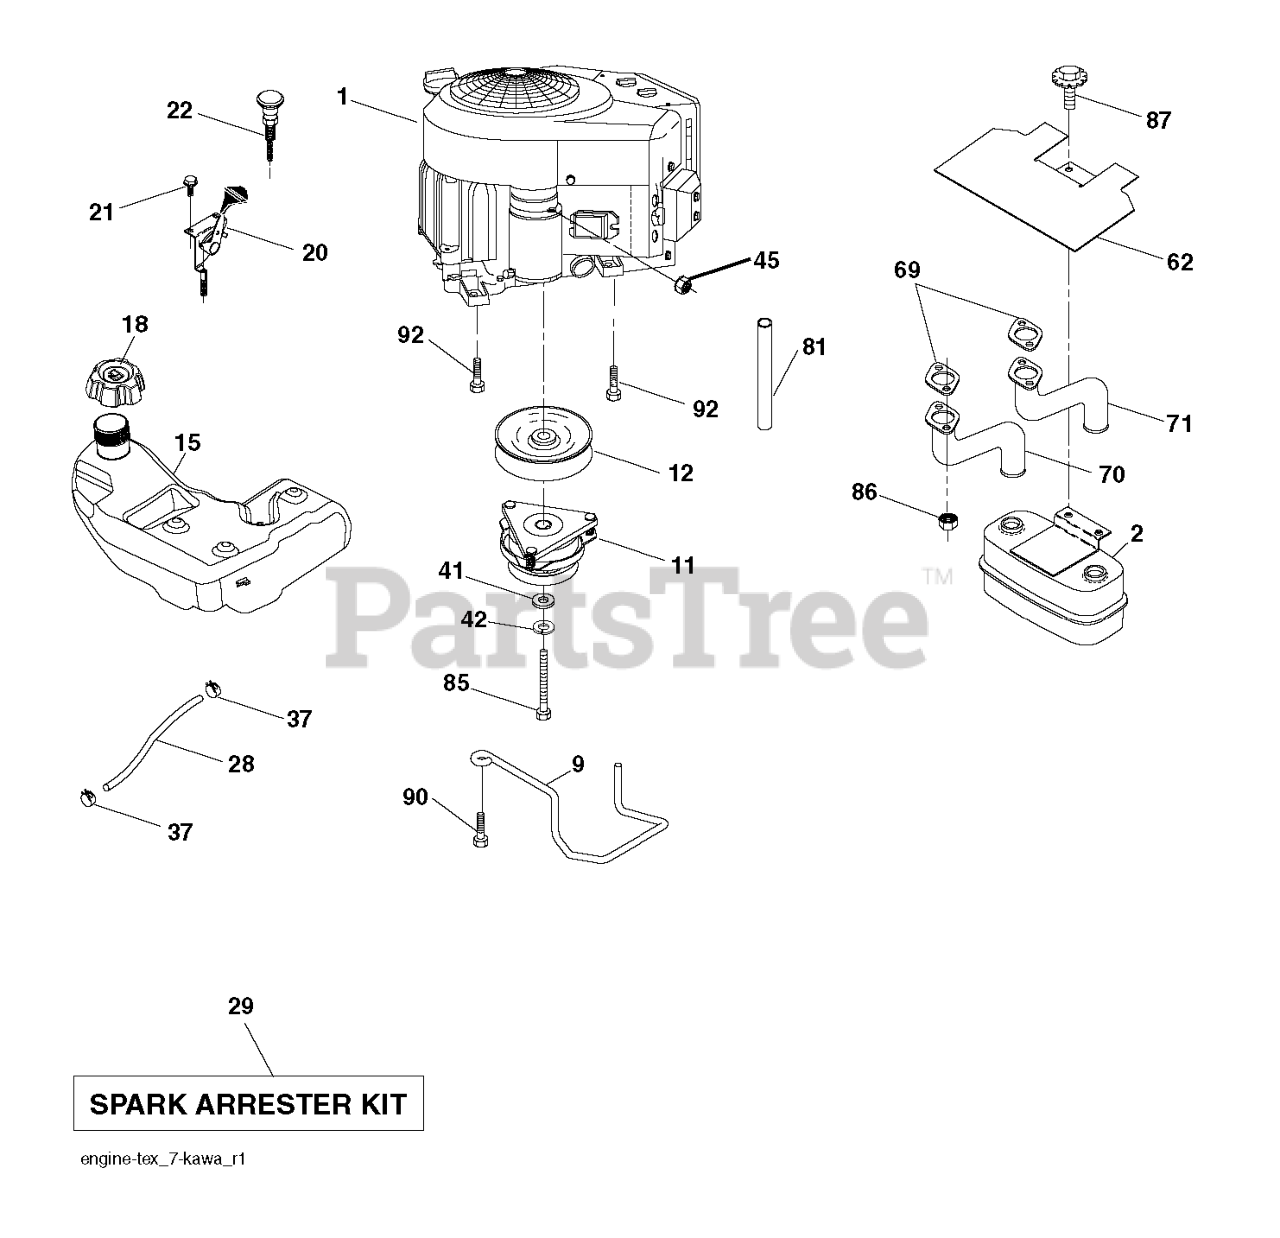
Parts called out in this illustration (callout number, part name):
2	MUFFLER.TWIN.CYL.LOW.TONE
9	KEEPER.BELT.ENGINE.4.2
11	RB.CLUTCH.OGURA.4.4.PD
12	PULLEY.ENGINE.TUFFTORQ
15	TANK.FUEL.4GAL
18	CAP.FUEL.TANK.3"GREY
20	THROTTLE CABLE
21	SCREW.#10 X 0.750.BOS
22	CONTROL.CHOKE.ERGO.PUSH-IN.BLA
28	REPL BY 532 00 85-43
29	KIT.SPARK ARRESTOR 794945 B&S
37	HOSE CLAMP
42	LOCKWASHER
45	NUT
62	RP SHIELD HEAT MUFFLER
69	GASKET.EXHAUST.KAWASAKI.15-1
70	EXHAUST TUBE LH KAWI
71	EXHAUST TUBE RH KAWI
81	TUBE, DRAIN OIL ASM.
85	BOLT HEX 7/16-20X4-1/4"
86	NUT.HEX.FLANGE.TOPLOCK
87	BOLT.5/16-18UNCX3/4 W/SEMS.BLK
90	SCREW 3/8-16X1
92	SCREW 3/8-16X1
